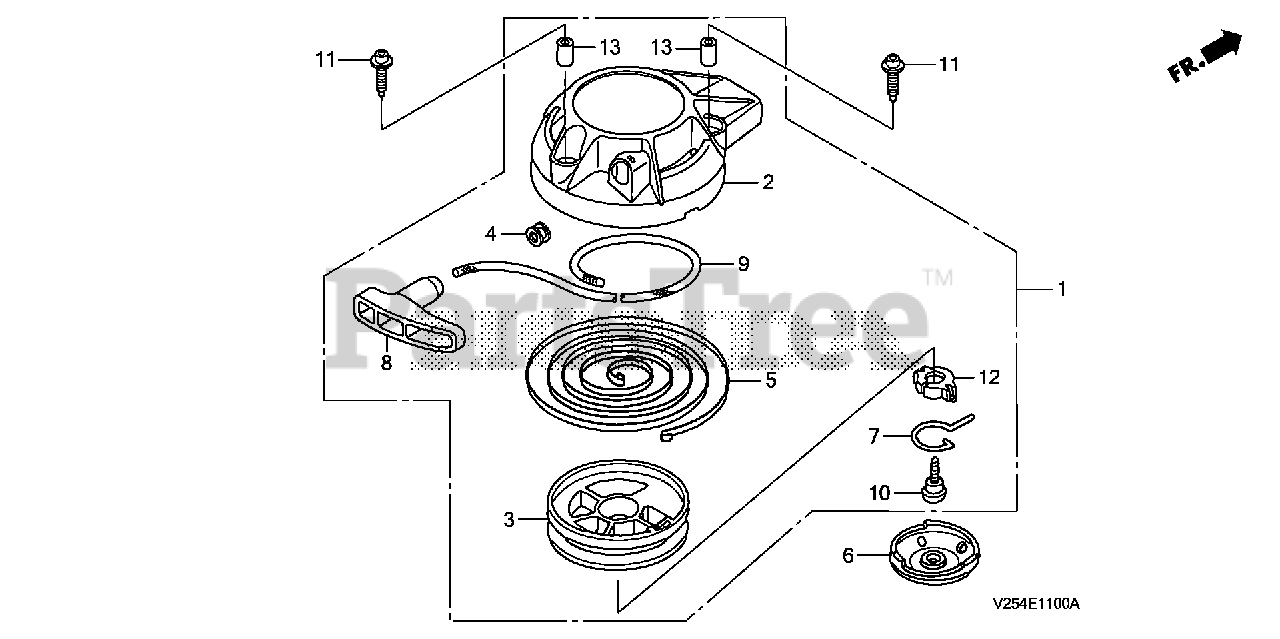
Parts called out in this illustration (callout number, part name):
1	STARTER ASSY., RECOIL
1	STARTER ASSY., RECOIL (FOR U.S.A.)
2	CASE, RECOIL STARTER
3	REEL, RECOIL STARTER
4	GUIDE, ROPE
5	SPRING, RECOIL STARTER
6	PULLEY, RECOIL STARTER
8	KNOB, RECOIL STARTER
9	ROPE, RECOIL STARTER (#3.5X40")
10	SCREW, SETTING
11	BOLT, SOCKET (5X16)
13	COLLAR A, HEAD COVER
